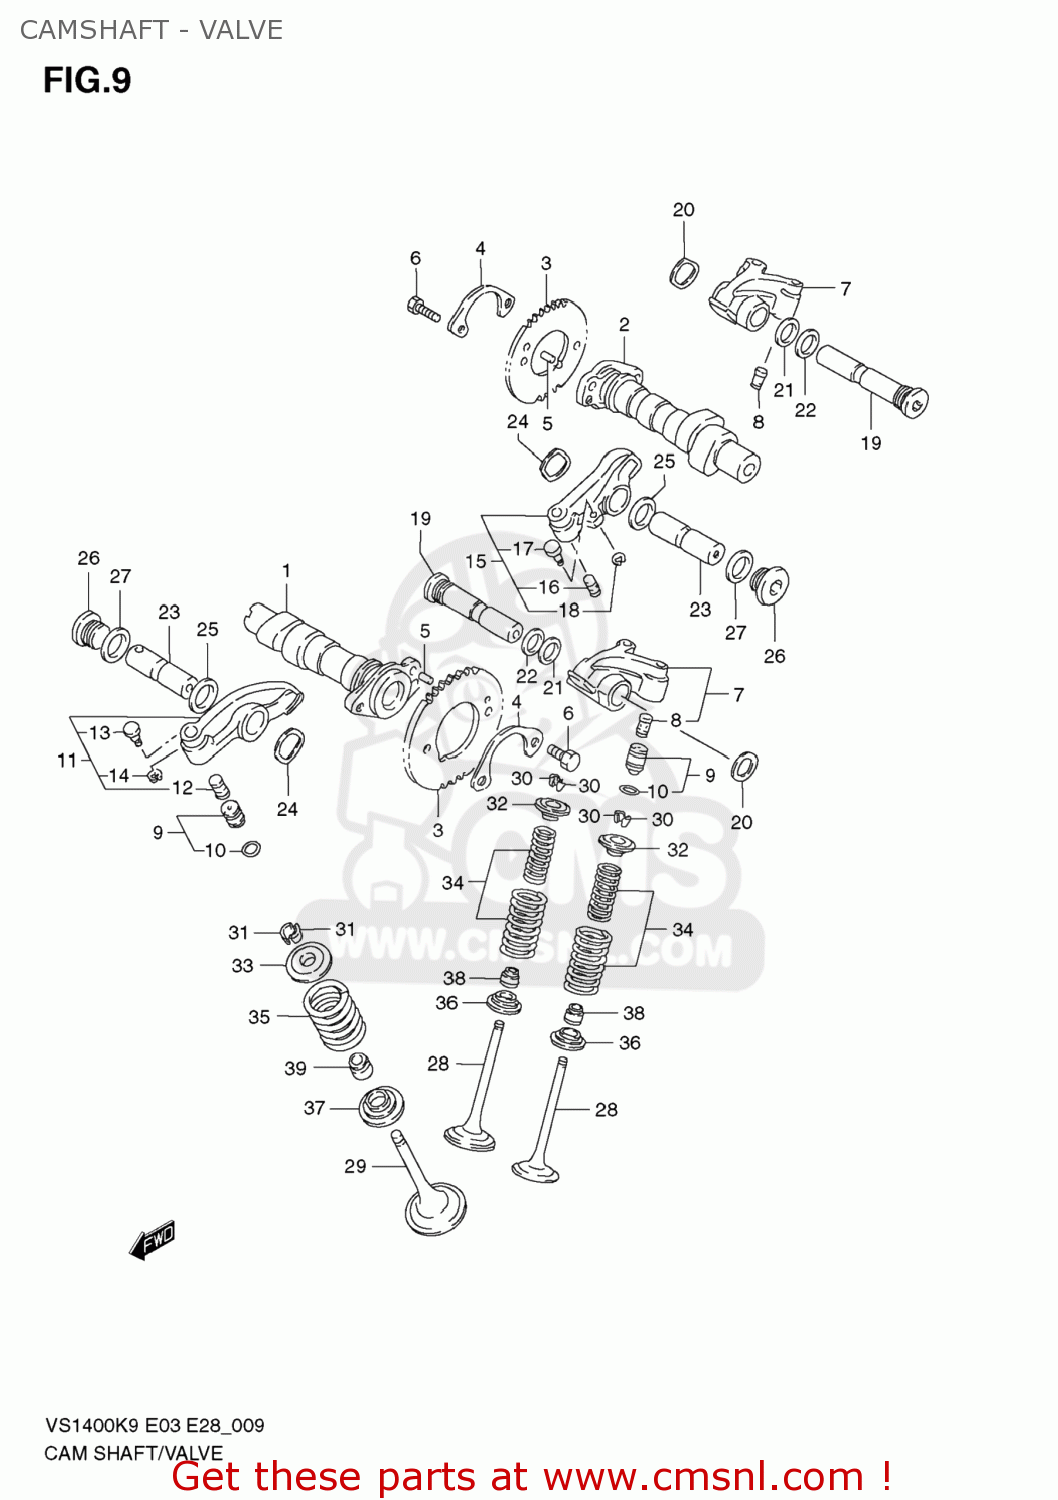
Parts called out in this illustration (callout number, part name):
1	CAMSHAFT,FR
2	CAMSHAFT,RR
3	SPROCKET,CAMSHAFT
4	WASHER,SPROCKET
5	PIN(5X8)
6	BOLT(6X12.5)
7	ARM,VALVE ROCKER INTAKE
8	CHAMBER,VALVE LASH ADJUSTER
9	ADJUSTER,HYDRAULIC VALVE LASH
10	O RING
11	ARM,VALVE ROCKER FR EXHAUST
12	CHAMBER,VALVE LASH ADJUSTER
13	PIN,DECOMP
14	E RING
15	ARM,VALVE ROCKER RR EXHAUST
16	CHAMBER,VALVE LASH ADJUSTER
17	PIN,DECOMP
18	E RING
19	SHAFT,INTAKE VALVE ROCKER ARM
20	WASHER
21	SHIM(14X20X1)
22	GASKET(16X22X2) (NAS)
23	SHAFT,EXHAUST VALVE ROCKER ARM
24	WASHER
25	WASHER(16X26X1)
26	PLUG,18X11
27	GASKET(18X24.2X2) (NAS)
28	VALVE,INTAKE
29	VALVE,EXHAUST
30	COTTER,VALVE
31	COTTER,VALVE
32	RETAINER,VALVE SPRING
33	RETAINER,VALVE SPRING
34	SPRING SET,VALVE
35	SPRING,VALVE OUTER
36	SEAT,VALVE SPRING
37	SEAT,VALVE SPRING
38	SEAL,OIL(5.5X11X8.2)
39	SEAL,OIL(7X14.4X9)
